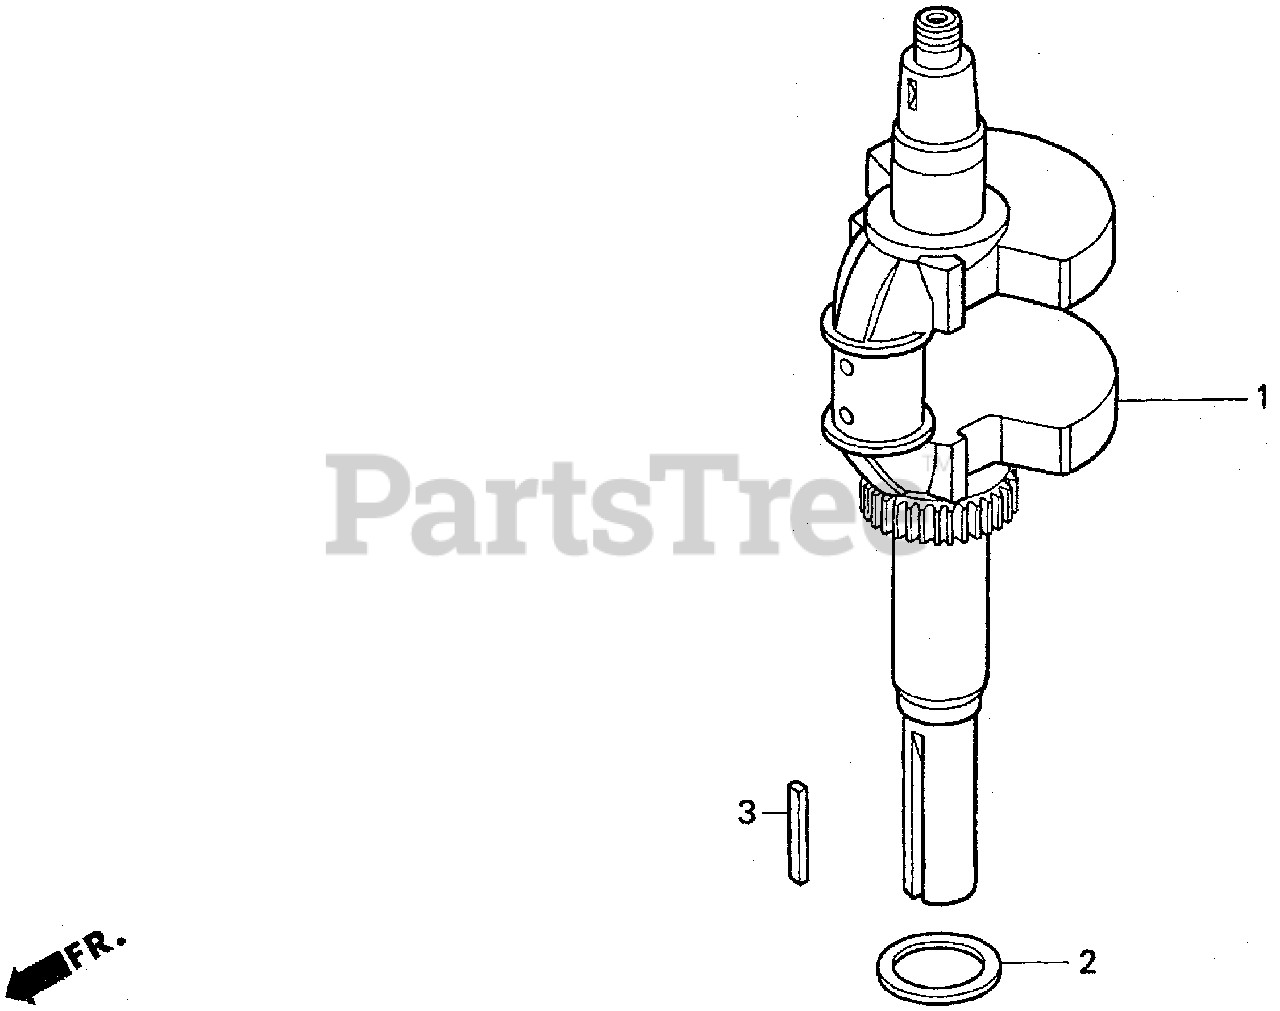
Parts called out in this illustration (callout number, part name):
1	CRANKSHAFT
2	WASHER, CRANKSHAFT THRUST
3	KEY (6.3X6.3X43)
